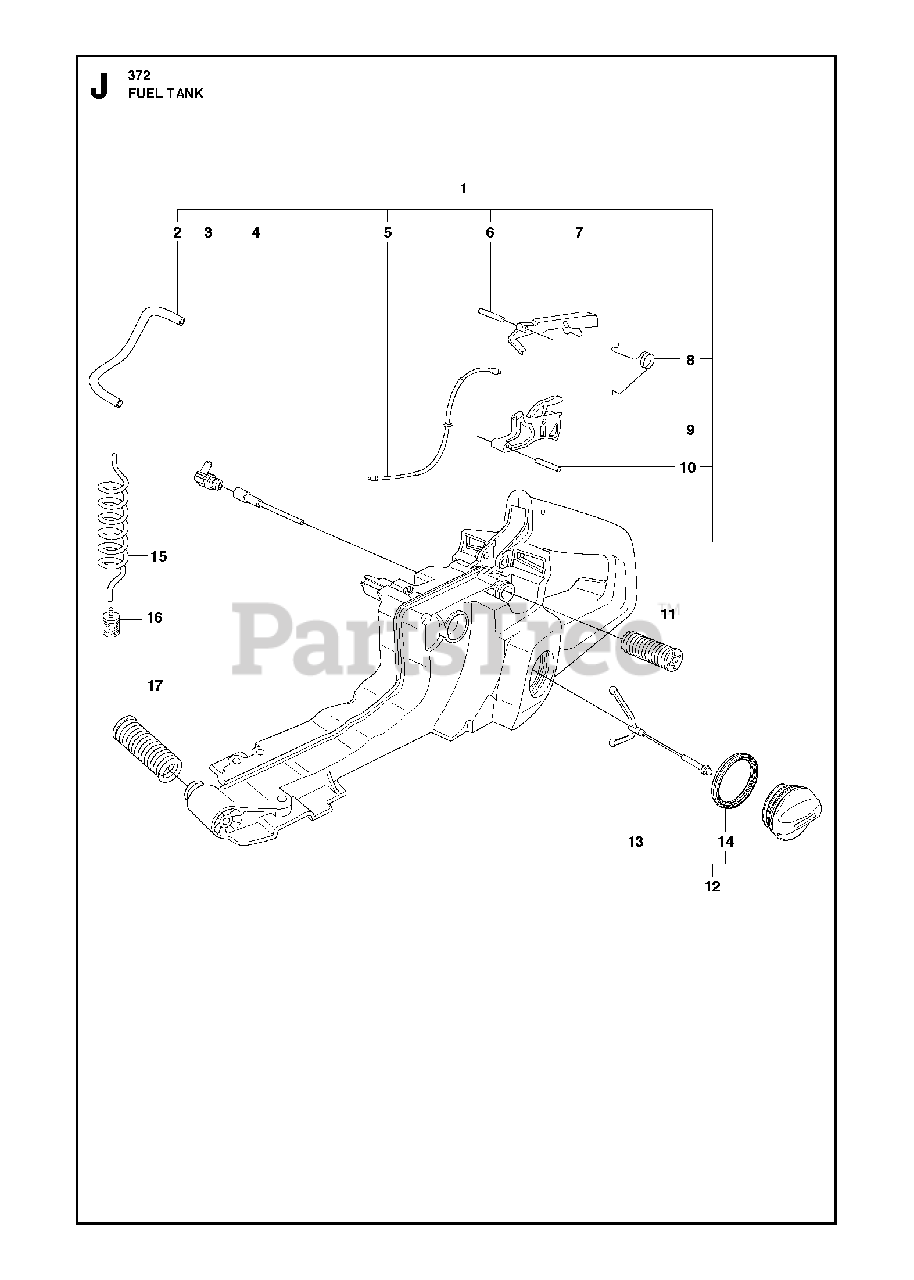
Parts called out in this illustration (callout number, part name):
1	TANK/HANDLE ASSY
2	HOSE
3	CONNECTOR
4	TANK VALVE
5	WIRE
6	PIN 3X25
7	THROTTLE CATCH
8	SPRING
9	THROTTLE TRIGGER
10	PIN CPH8 4X20
11	ANTIVIBE MOUNT
12	TANK CAP
13	TANK LOCK
14	SEALING
15	FUEL HOSE
16	FUEL FILTER
17	ANTIVIBE MOUNT
17	AV SPRING (HARD)
